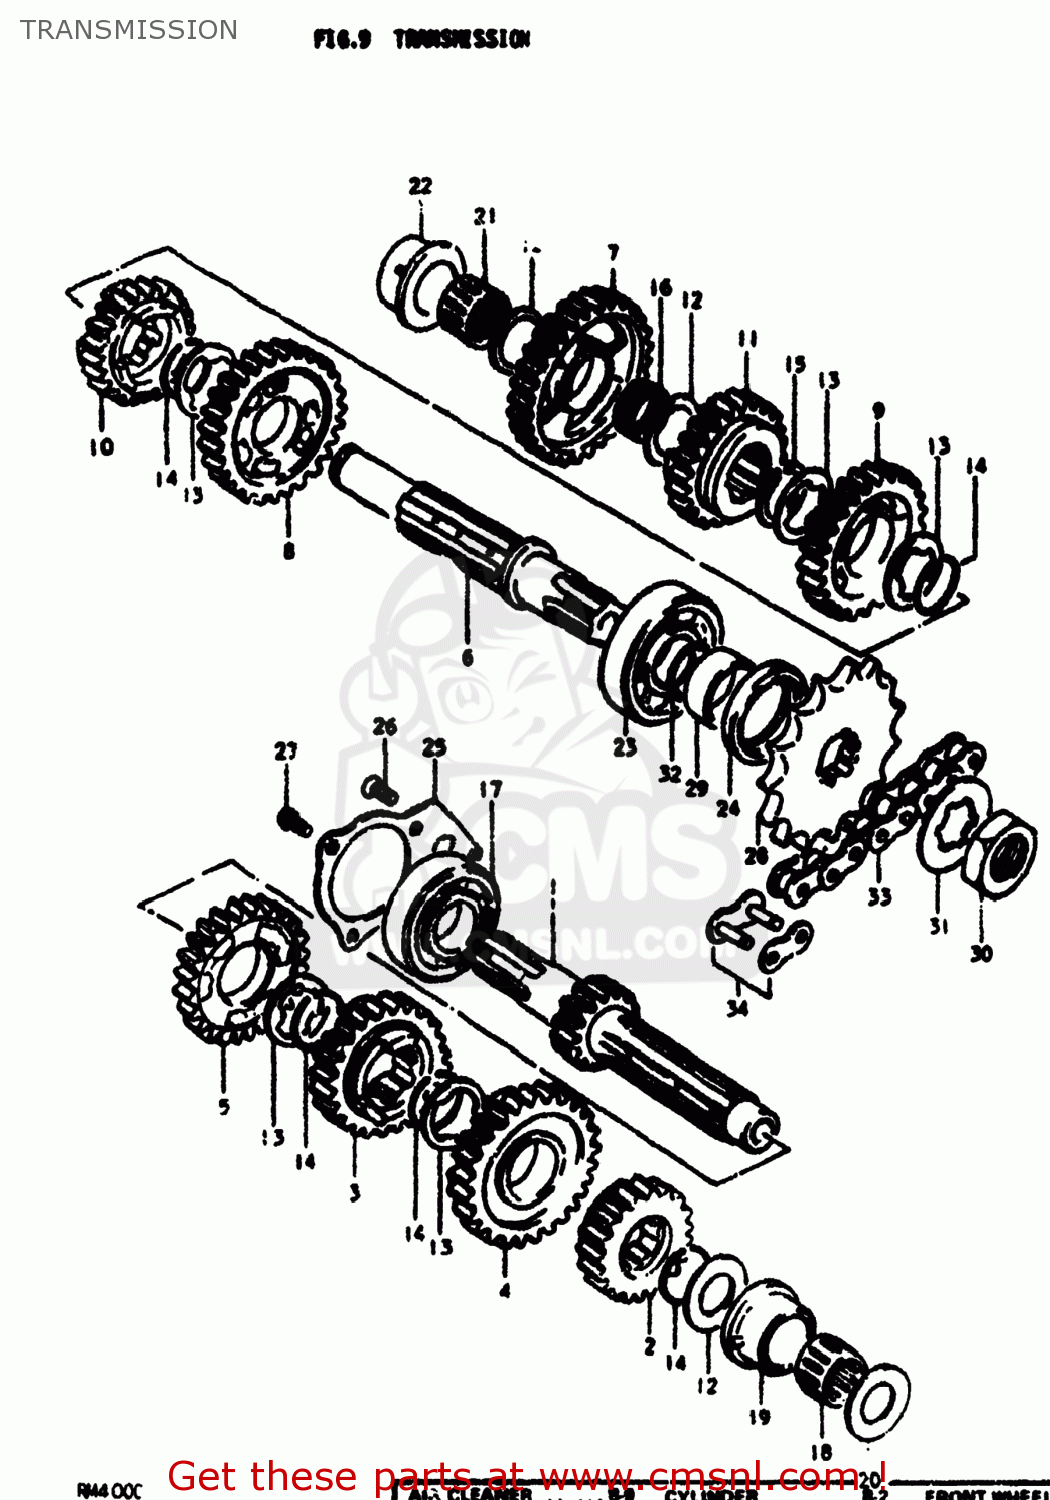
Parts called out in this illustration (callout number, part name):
1	SHAFT,COUNTER
2	GEAR,SECOND DRIVE
3	GEAR,THIRD DRIVE
4	GEAR,FOURTH DRIVE
5	GEAR,FIFTH DRIVE
6	SHAFT,DRIVE
7	GEAR,FIRST DRIVEN
8	GEAR,SECOND DRIVEN
9	GEAR,THIRD DRIVEN
10	GEAR,FOURTH DRIVEN
11	GEAR,FIFTH DRIVEN
12	WASHER (20X30X1)
13	WASHER,LOCK
14	RING,SNAP
15	CIRCLIP
16	BEARING(20X24X10).8
17	BEARING
18	BEARING(20X24X16.8)
19	BUSHING
20	WASHER (20X30X1)
21	BEARING(20X24X16.8)
22	BUSHING
23	BEARING
24	SEAL,OIL(32X42X6)
25	PLATE,COUNTERSHAFT BEARING
26	SCREW
27	SCREW 6X12
28	SPROCKET,ENGINE
29	SPACER(22X32X11.5)
30	NUT
31	WASHER,LOCK
32	O RING(D:1.7,ID:22)
33	CHAIN ASSEMBLY,DRIVE
34	JOINT ASSEMBLY,CHAIN
